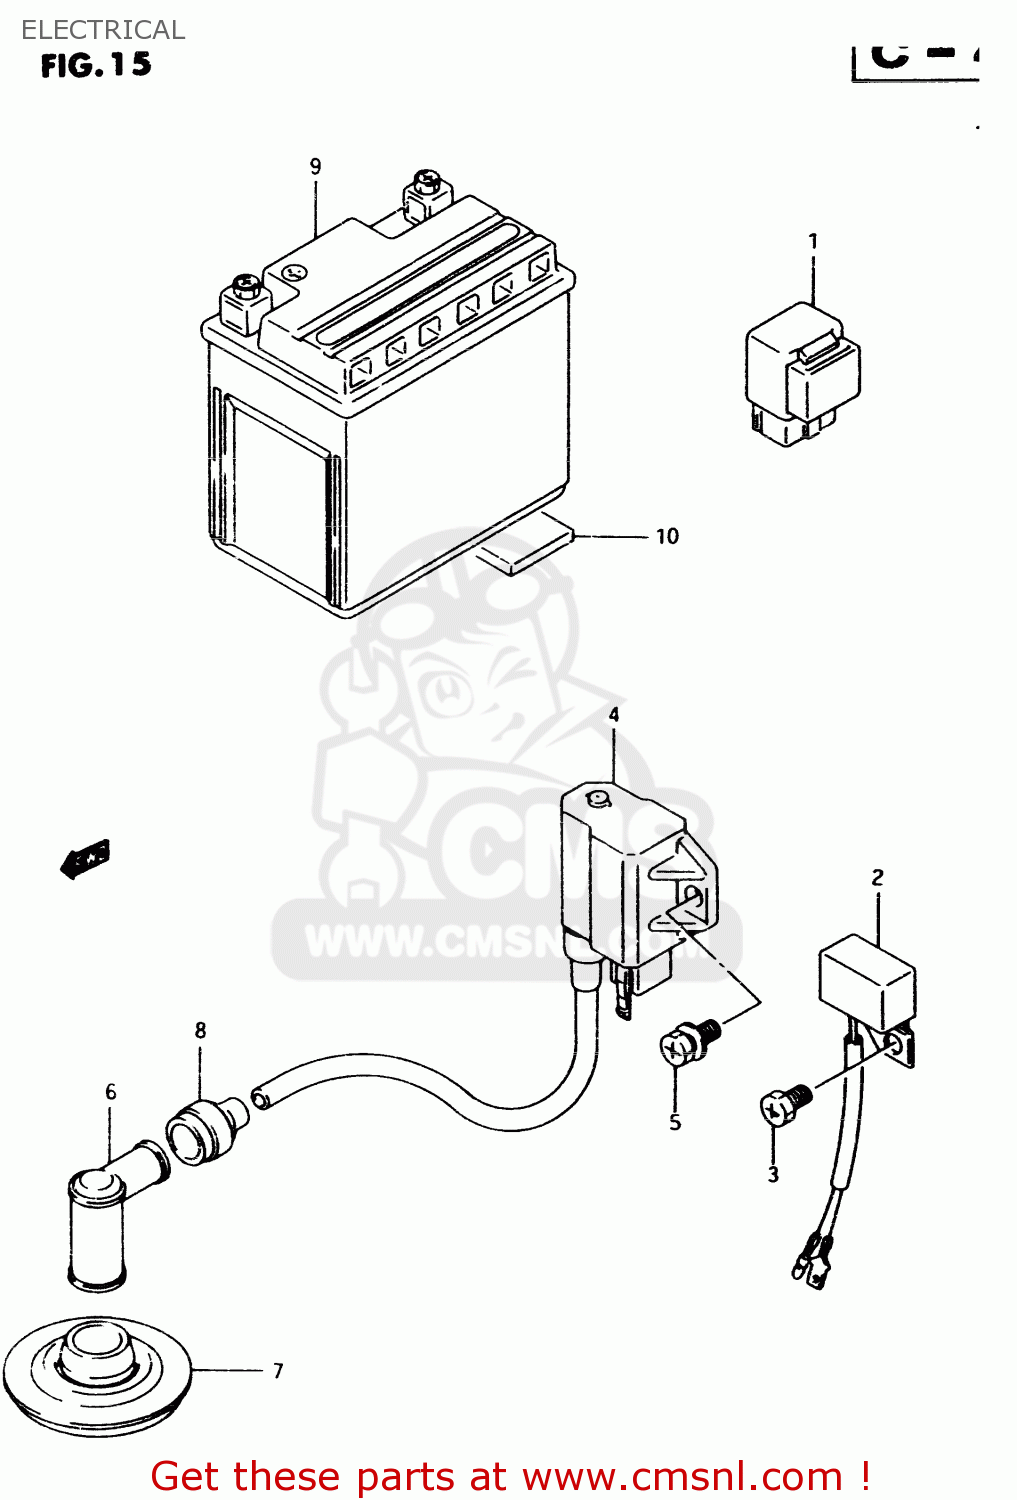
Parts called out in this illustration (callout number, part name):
1	RELAY ASSY,STARTING MOTOR
2	RECTIFIER ASSY
3	SCREW(6X10)
4	UNIT & COIL ASSY,IGNITION
5	SCREW
6	CAP ASSY,SPARK PLUG
7	BOOT,SPARK PLUG CAP
8	SEAL,HIGH TENSION CORD
9	BATTERY ASSY(YTX5L-BS,12V4.2AH
10	PROTECTOR(170X95X3.0)
